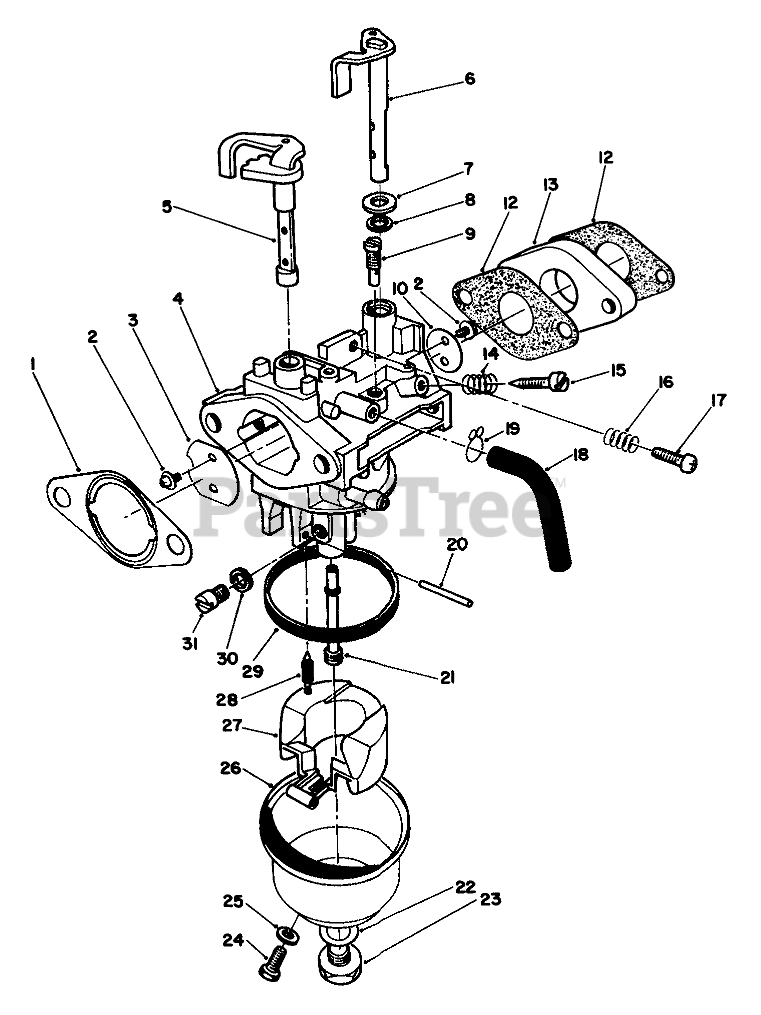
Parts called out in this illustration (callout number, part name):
1	GASKET F/W ENGINE
2	Screw
3	VALVE
4	Body-Carburetor
5	SHAFT
6	SHAFT
7	WASHER
8	Seal-Throttle Shaft
9	PILOT JET
10	VALVE
12	Gasket-Carburetor
13	CARB INSULATOR
14	SPRING-PILOT SCREW
15	ADJUSTER
16	Spring-Idle Stop
17	SCREW
19	CLAMP
20	Pin
21	NOZZLE
22	GASKET
23	SCREW
24	SCREW
25	GASKET
27	Float
28	NEEDLE
29	FLOAT BOWL GASKET
30	SPACER
31	MAIN JET
